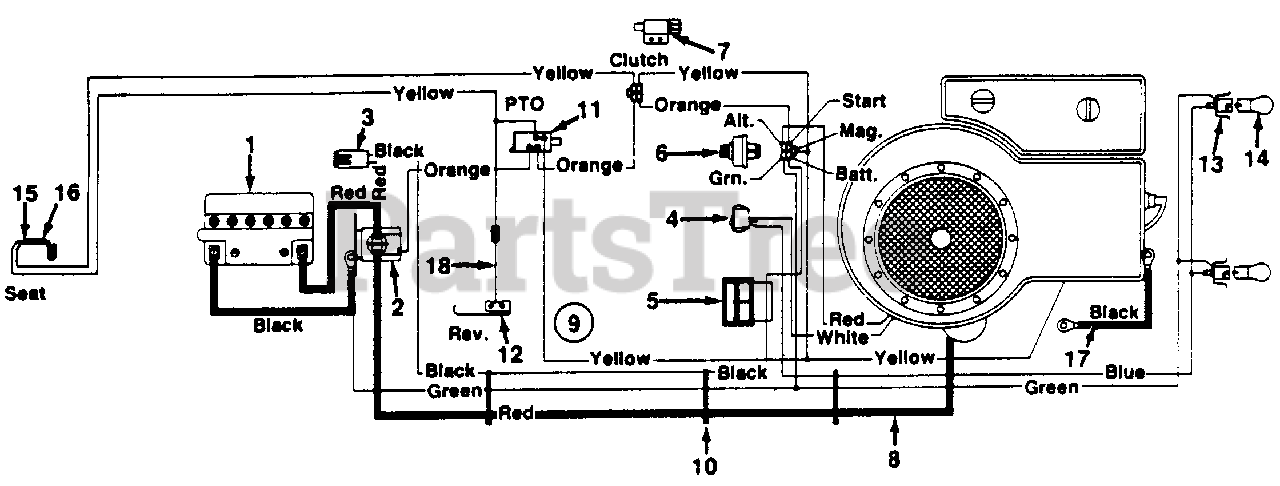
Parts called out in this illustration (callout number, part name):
1	Battery
2	Solenoid
3	Fuse 7-1/2 Amp
4	Light Switch
5	Ammeter
6	Ignition Switch
7	Safety Switch
8	Electric Wire-30" Lg.
9	Wire Harness
11	Safety Switch
12	Safety Switch
13	Socket
14	Bulb
15	Safety Switch
16	Safety Switch
17	Ground Wire 7.5" Lg.
18	Ext. Wire
